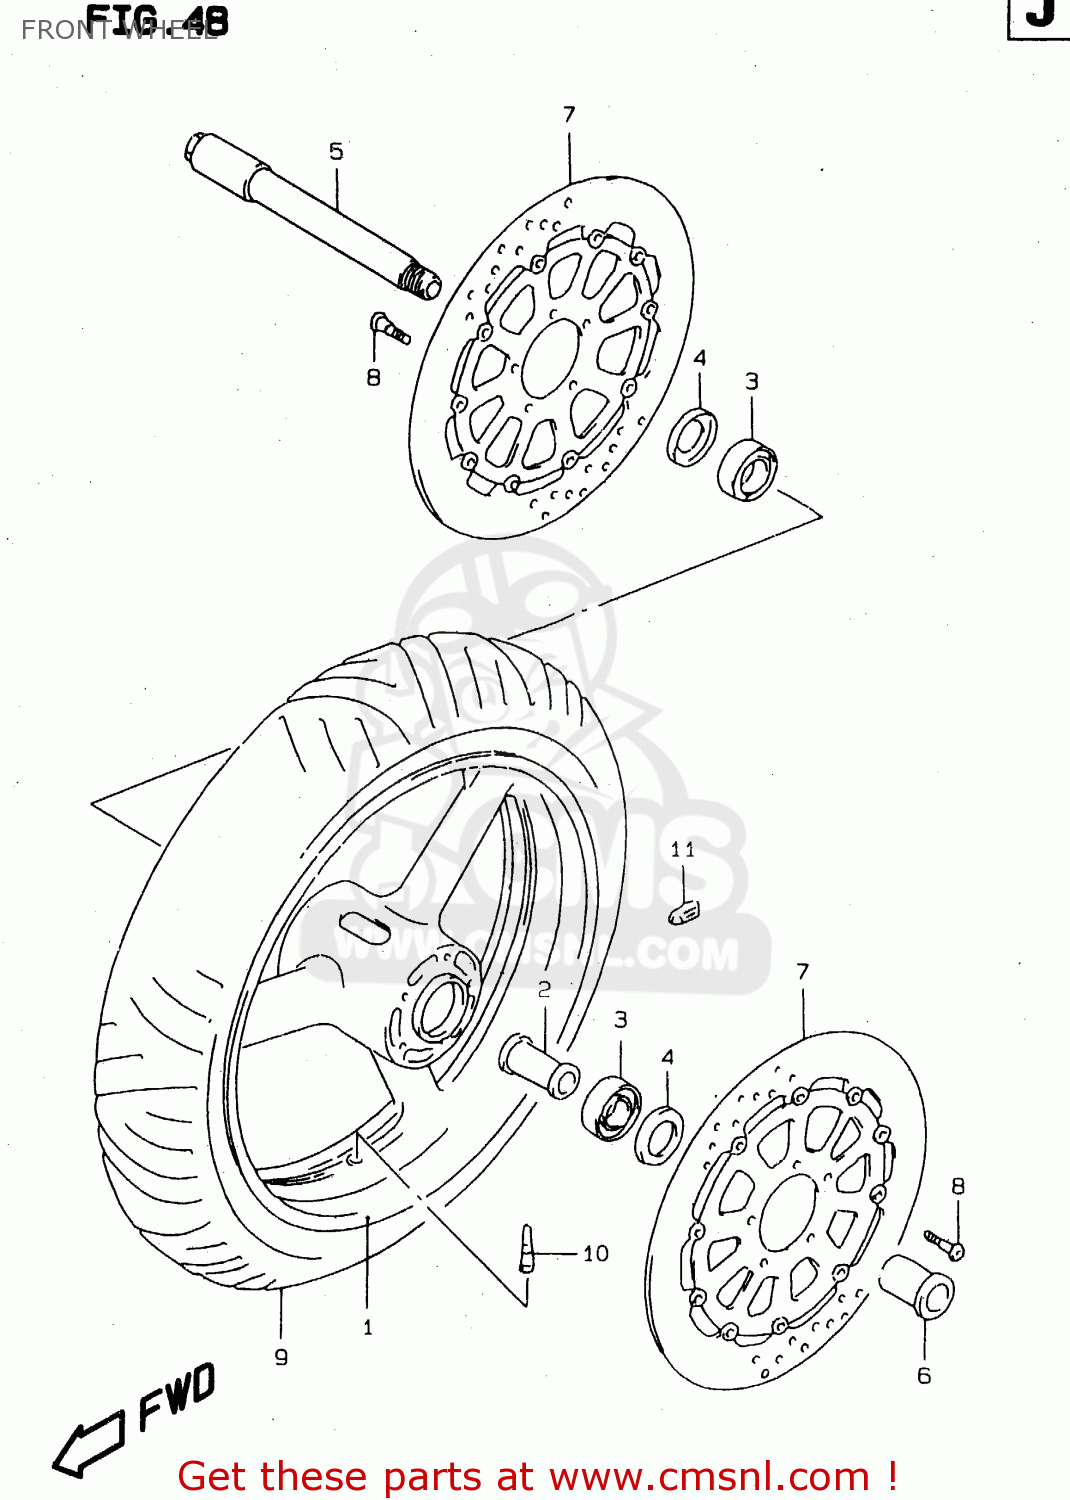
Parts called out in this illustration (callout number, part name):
1	WHEEL,FRONT (17XMT3.50)(
2	SPACER,FR HUB BEARING
3	BEARING(25X52X15)
4	SEAL,OIL(32X52X7)
5	AXLE,FR
6	NUT,FR AXLE
7	DISC,FR BRAKE
8	BOLT 8X33
9	TIRE 120/70 ZR17 (58W),M
10	VALVE ASSY,WHEEL RIM(TR412)
11	BALANCER,WHEEL (10G)
